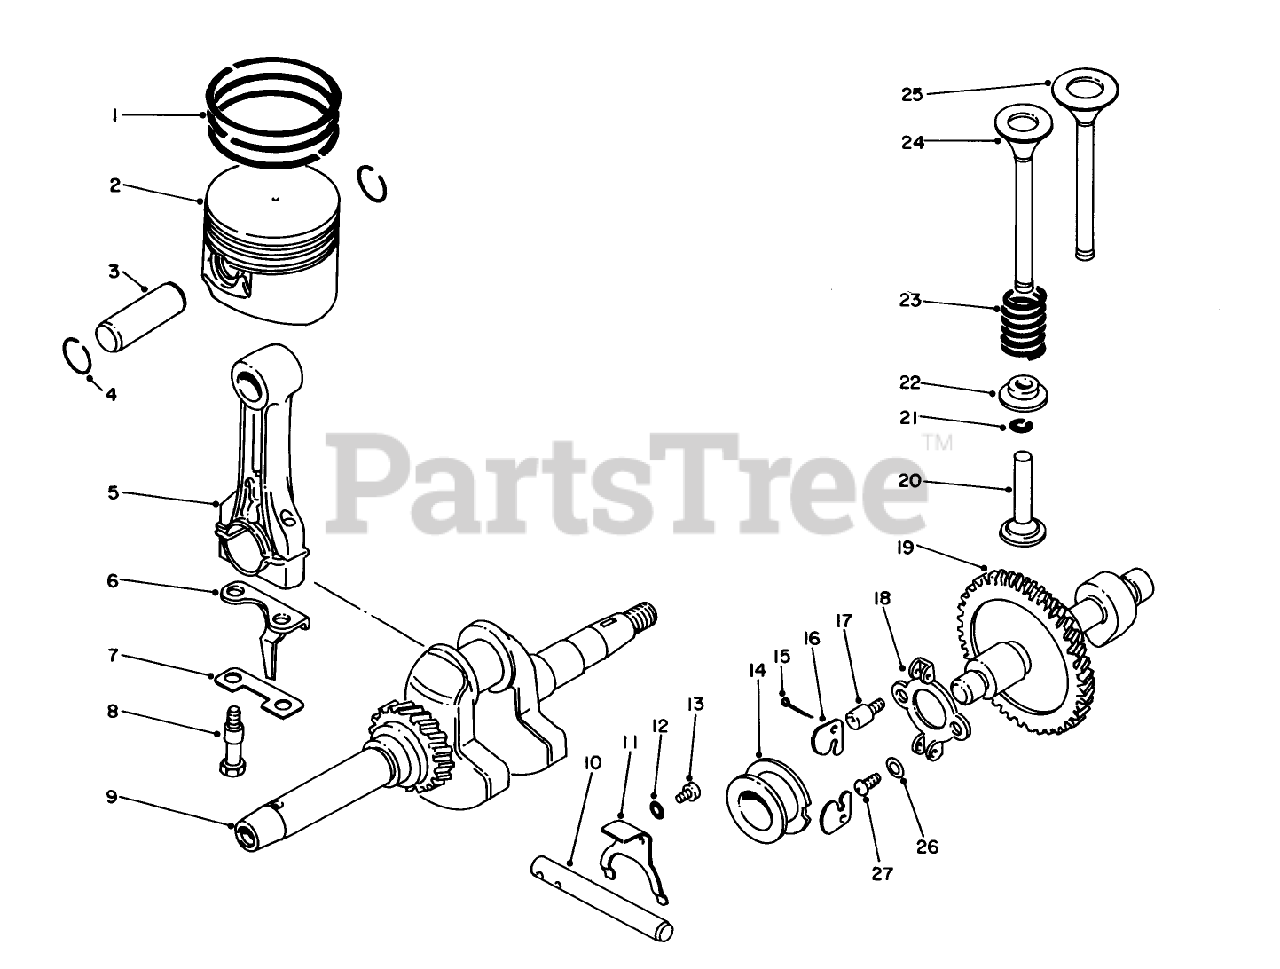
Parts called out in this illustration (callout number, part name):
1	Ring Set-Piston Std.
2	Piston Std.
3	Pin Piston
4	CIRCLIP
5	Rod-Connecting (Incl. Ref. # 6-8)
6	Plate-Splasher
7	LOCK PLATE
9	Crankshaft
10	SHAFT-THROTTLE TURN
11	SHIFT PLATE
12	Washer
13	SCREW
14	Spacer
15	Cotter Pin
18	BRACKET
19	Cam Shaft
20	TAPPET
21	Cotter-Valve
22	Retainer-Spring
23	Spring-Valve
24	VALVE, EXHAUST
25	VALVE, INTAKE
26	Washer
